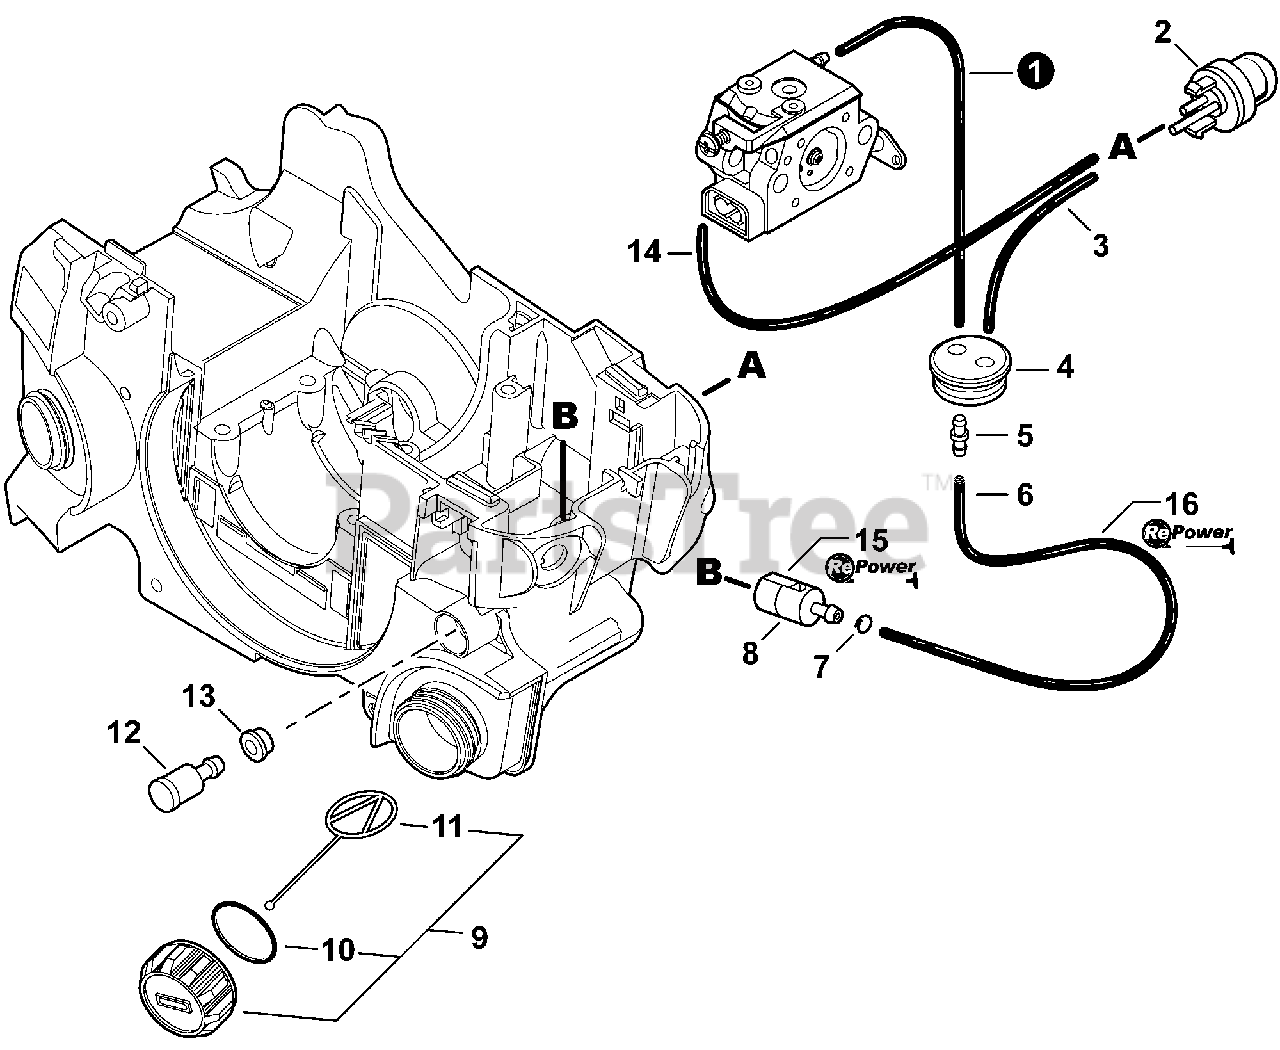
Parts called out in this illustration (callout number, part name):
1	PIPE, FUEL 3×5×85 BLACK
2	BULB, PURGE
3	PIPE, FUEL 2.4×5×80 BLACK
4	GROMMET, FUEL
5	CONNECTOR, PIPE
6	PIPE, FUEL 3×5×144 BLACK
7	CLIP Ø6
8	FILTER, FUEL
9	CAP ASSY, FUEL
10	O-RING 22
11	CONNECTOR, CAP L= 60 MM
12	VENT ASSY
13	GROMMET, FUEL
14	PIPE 2.4×5×125 BLACK
15	TUNE-UP KIT - REPOWER
16	BULK PIPE - 3×5 MM BLACK (4 PIECES×2 M)
